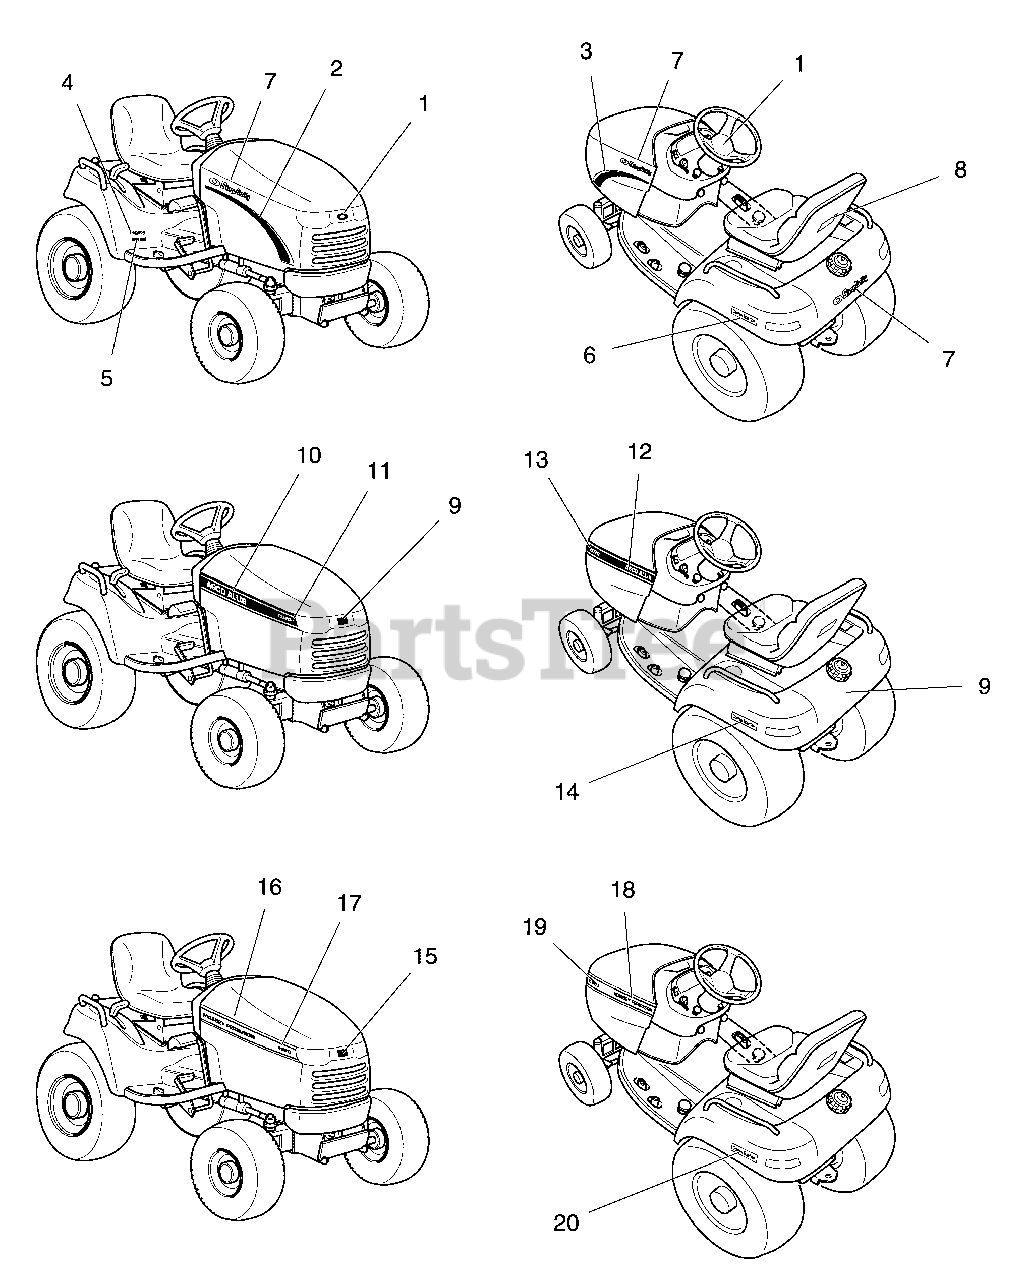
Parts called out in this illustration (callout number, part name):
1	ICON, Simplicity
2	DECAL, RH Stripe & Logo (Simplicity Models)
3	DECAL, LH Stripe & Logo (Simplicity Models)
4	DECAL, Legacy
5	DECAL, Model, 20V Twin (Simplicity Models)
5	DECAL, Model, 25V Twin (Simplicity Models)
5	DECAL, Model, 20 Liquid-Cooled (Simplicity Models)
6	DECAL, Control Traction (Simplicity Models)
7	DECAL, Simplicity Logo
8	DECAL, USA Logo
9	DECAL, AGCO Allis Logo
10	DECAL, RH Stripe & Logo (AGCO Allis Models)
11	DECAL, RH Model, 2020 (AGCO Allis Models)
11	DECAL, RH Model, 2020LC (AGCO Allis Models)
11	DECAL, RH Model, 2025 (AGCO Allis Models)
12	DECAL, LH Stripe & Logo (AGCO Allis Models)
13	DECAL, LH Model, 2020 (AGCO Allis Models)
13	DECAL, LH Model, 2020LC (AGCO Allis Models)
13	DECAL, LH Model, 2025 (AGCO Allis Models)
14	DECAL, Control Traction (AGCO Allis & Massey Ferguson Models)
15	DECAL, Massey Ferguson Logo
16	DECAL, RH Stripe & Logo (Massey Ferguson Models)
17	DECAL, RH Model, 2920 (Massey Ferguson Models)
17	DECAL, RH Model, 2920LC (Massey Ferguson Models)
17	DECAL, RH Model, 2925 (Massey Ferguson Models)
18	DECAL, LH Stripe & Logo (Massey Ferguson Models)
19	DECAL, LH Model, 2920 (Massey Ferguson Models)
19	DECAL, LH Model, 2920LC (Massey Ferguson Models)
19	DECAL, LH Model, 2925 (Massey Ferguson Models)
20	DECAL, Control Traction (AGCO Allis & Massey Ferguson Models)
